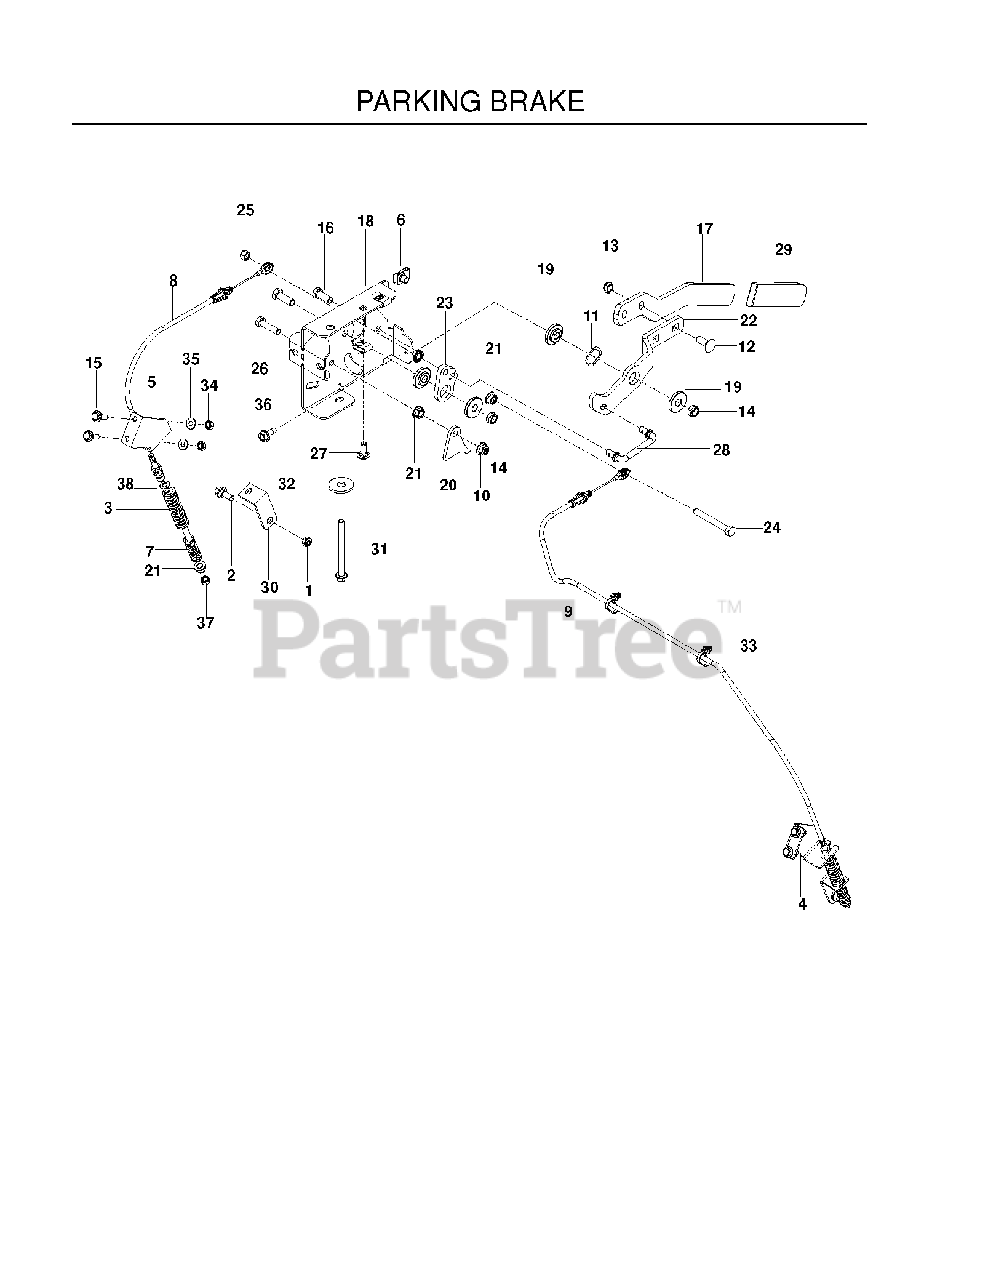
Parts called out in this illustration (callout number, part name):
1	5/16-18 THIN PROF NY
2	BOLT, SHOULDER
3	SPRING, RETURN
4	BRKT, BRAKE RT, BLK
5	BRKT, BRAKE LT, BLK
6	U-CLIP 5/16-18 NUT RETAINER
7	SPRING, ENGAGEMENT
8	CABLE, BRAKE, SHORT
9	CABLE, BRAKE, LONG
10	5/16-18 NYLOC FLANGE NUT
11	WASHER, .825 X 1.087, WAVE
12	RHSNB 3/8C X 1
13	NUT 3/8-16 HEX FLG NYLOC ZD
14	NUT HEX 3/8-16 NYLON, THIN
15	HCS 1/4-20X7/8 GR5
16	HCS 3/8C X 1
17	ARM, BRAKE, BLACK
18	MOUNT, BRAKE WLDMT
19	BUSHING, BRAKE
20	ACTUATOR, SWITCH
21	NUT 5/16C WHIZ
22	LEVER, BRAKE
23	BELLCRANK, BRAKE
24	HCS 5/16-18 X 2 1/2 TPBLT
25	NUT 5/16 NYLOC
26	HCS 5/16C X 1
27	BOLT 5/16C X 3/4" CARRIAGE
28	LINKAGE, BRAKE
29	GRIP BRAKE HANDLE
30	BRKT, BRAKE, BLK
31	HHFS 5/16-18 X 3 3/4
32	WASH USS FLAT 1/2
33	TIE WRAP, 8-3/8", W/CLIP
34	NUT 1/4-20 NYLOC
35	WASHER 1/4 SAE
36	BOLT 5/16-18 X 3/4
37	NUT 5/16-18 HEX JAM ZD
38	WASHER 3/8 SAE FLAT
